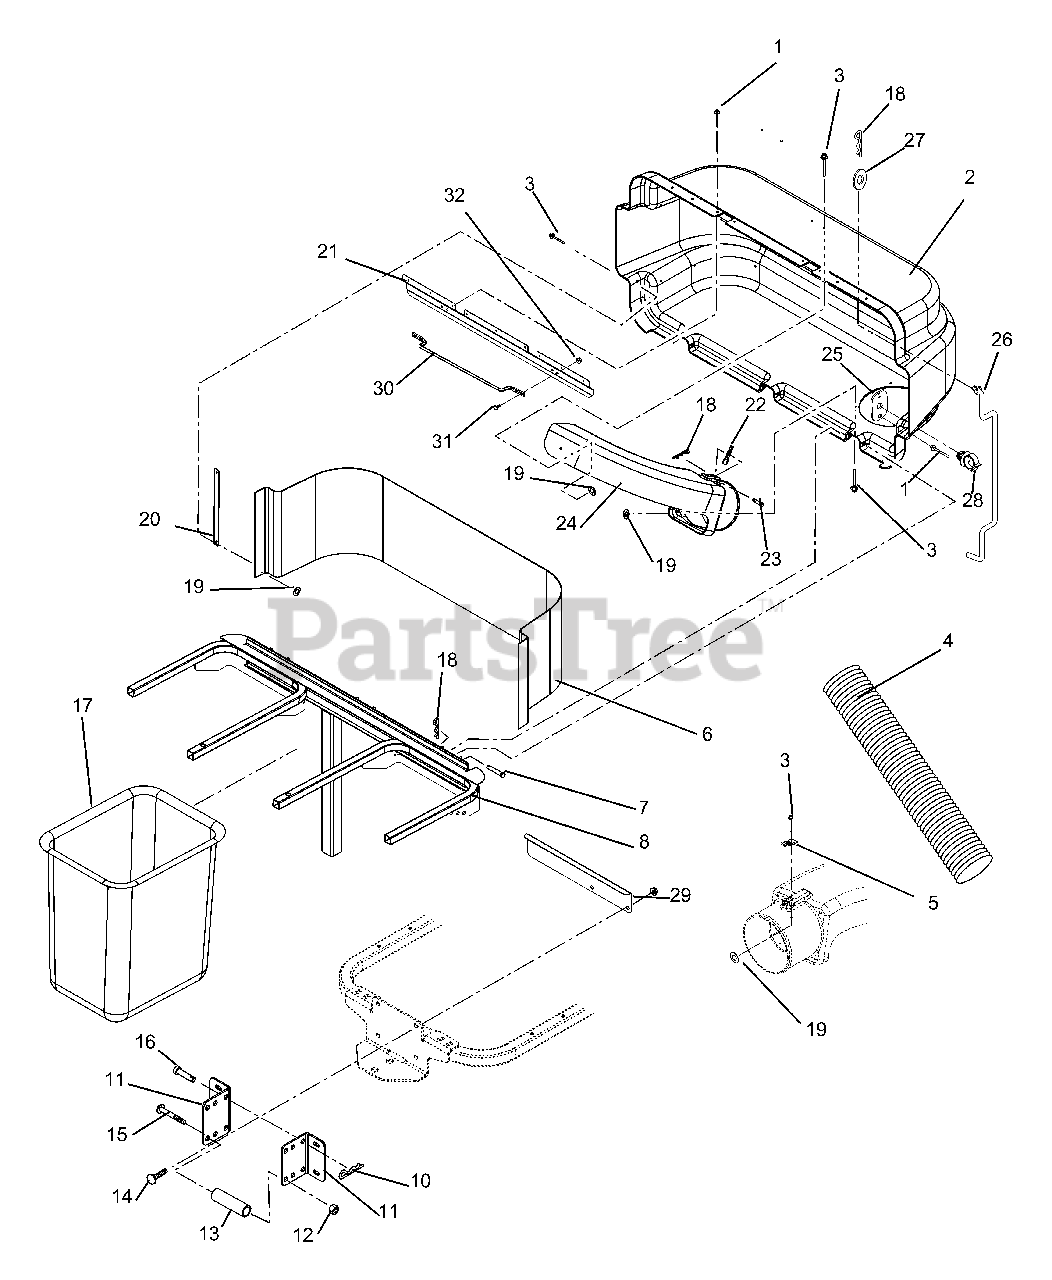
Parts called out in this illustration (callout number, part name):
1	RVT-POP .187X.402 DOME ST
2	BAGGER COVER W/DECAL
3	RVT-POP .187X.375
4	HOSE,7X45 KANAFLEX 165CL
5	THUMB LATCH
6	SCREEN, BAGGER
7	PIN-CLEV .371X3.25 YWZC
8	WMT,BAGGER FRAME
9	@NUT-LK-TOP-FLG .38-16 YWZC
10	PIN-HAIR-EXT .12X.31X2.37 YWZC
11	BKT,BAGGER MOUNT
12	@NUT-LK-TOP-FLG .50-13 YWZC
13	SPACER, PIVOT .500X.750X1.805
14	@BLT-RDHDSQNK .38-16X1.25 G5YZ
15	@BLT-HEX .50-13X3.00 GR5 YWZC
16	PIN-CLEV .494X2.50 BRIGHT ZINC
17	GRASS BAGGER BASKET
18	PIN-HAIR, ENDRIES #25 YWZC
19	@WSHR-FL-STL.219X.50X.049 YWZC
20	STRAP,COVER
21	LATCH, BAGGER (ZOOM)
22	INDICATOR, FLOW
23	PIN-CLEV .309 X 1.625 YWZC
24	BOOT,UPPER
25	PLATE, ROD CLIP
26	PROP-ROD, BAGGER
27	@WSHR-FL-STL.406X.812X.065 YWZ
28	CLIP-.38
29	DEFLECTOR, EXHAUST
30	BAGGER HANDLE
31	@BLT-RDHDSQNK .25-20X.75 G5YZ
32	NUT-LUG .50-20 YWZC
